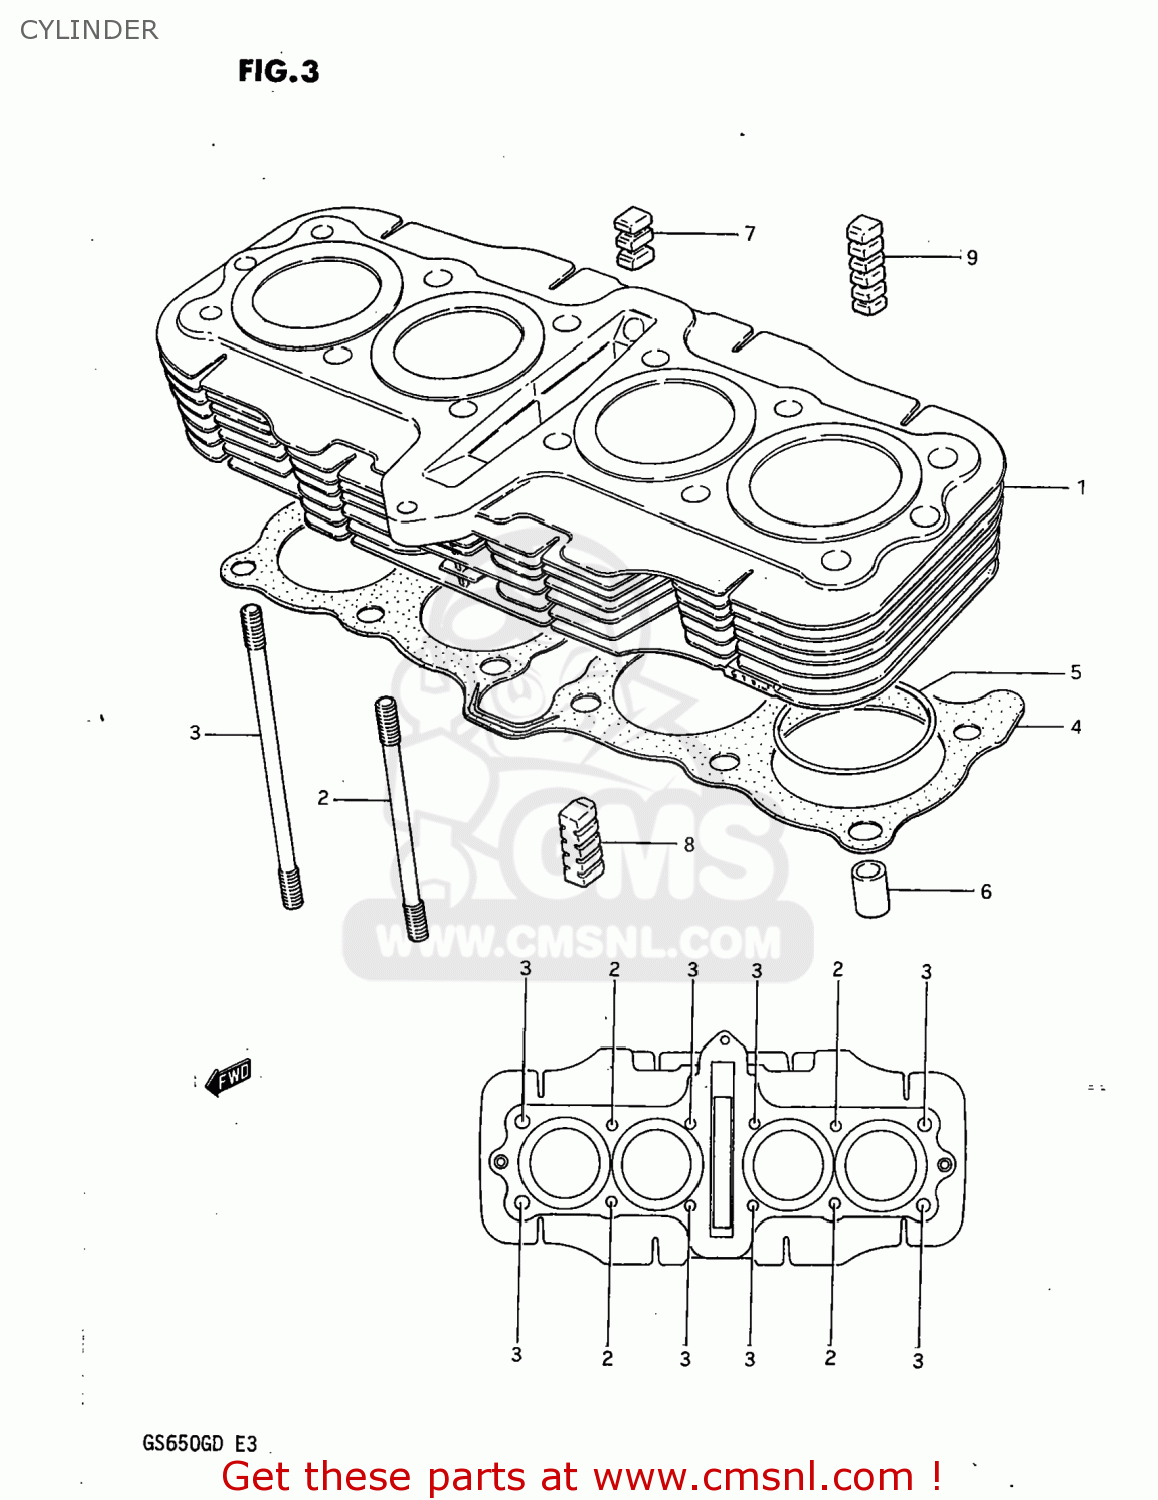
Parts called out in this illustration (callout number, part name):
1	CYLINDER
2	BOLT,STUD
3	BOLT,STUD
4	GASKET,CYLINDER (MCA)
5	O RING(D:2,ID:61)
6	PIN
7	PAD,CYLINDER
8	PAD,CYLINDER
9	PIN,EXHAUST VALVE
